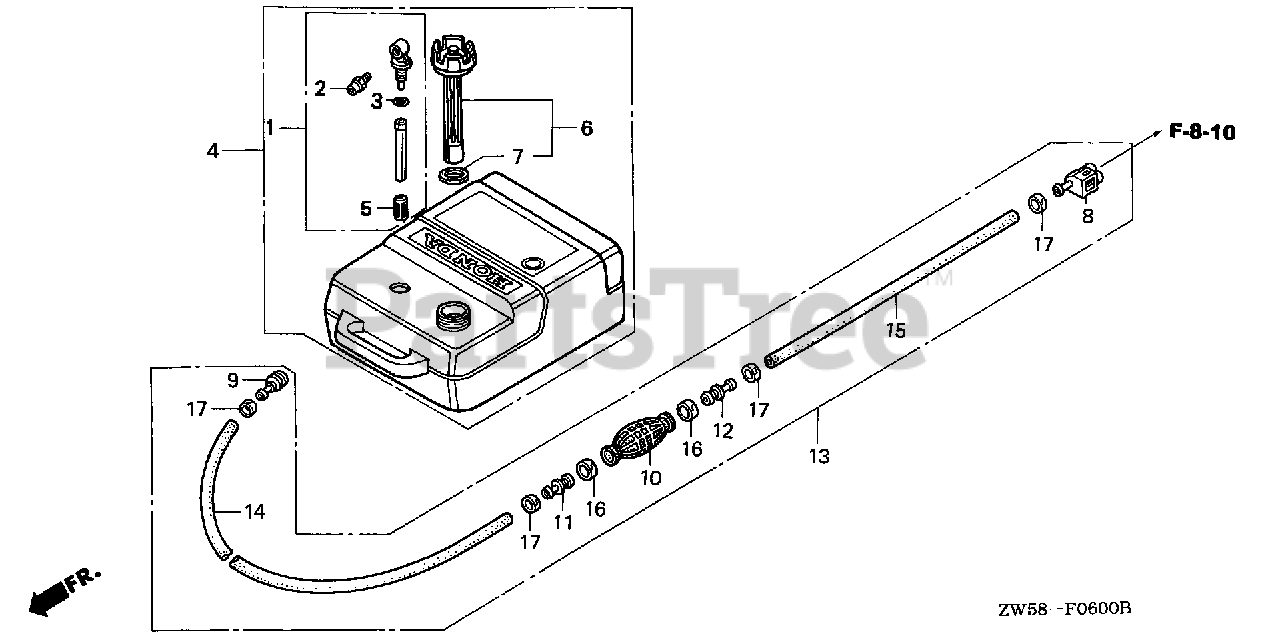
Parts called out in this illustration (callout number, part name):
1	JOINT ASSY., FUEL
2	FITTING, QUICK DISCONNECT
3	O-RING
4	TANK ASSY., FUEL
5	FILTER, FUEL
6	CAP, FUEL FILLER
7	GASKET, FUEL CAP
8	CONNECTOR ASSY., FUEL (A)
9	CONNECTOR, FUEL
10	BULB, PRIMER
11	VALVE, IN.
12	VALVE, OUTLET
13	TUBE ASSY., FUEL
14	TUBE, FUEL LONG (7.3X2000)
15	TUBE, FUEL SHORT (6.3X500)
16	BAND, TUBE CLIP (20MM)
17	BAND, TUBE CLIP (12.5MM)
